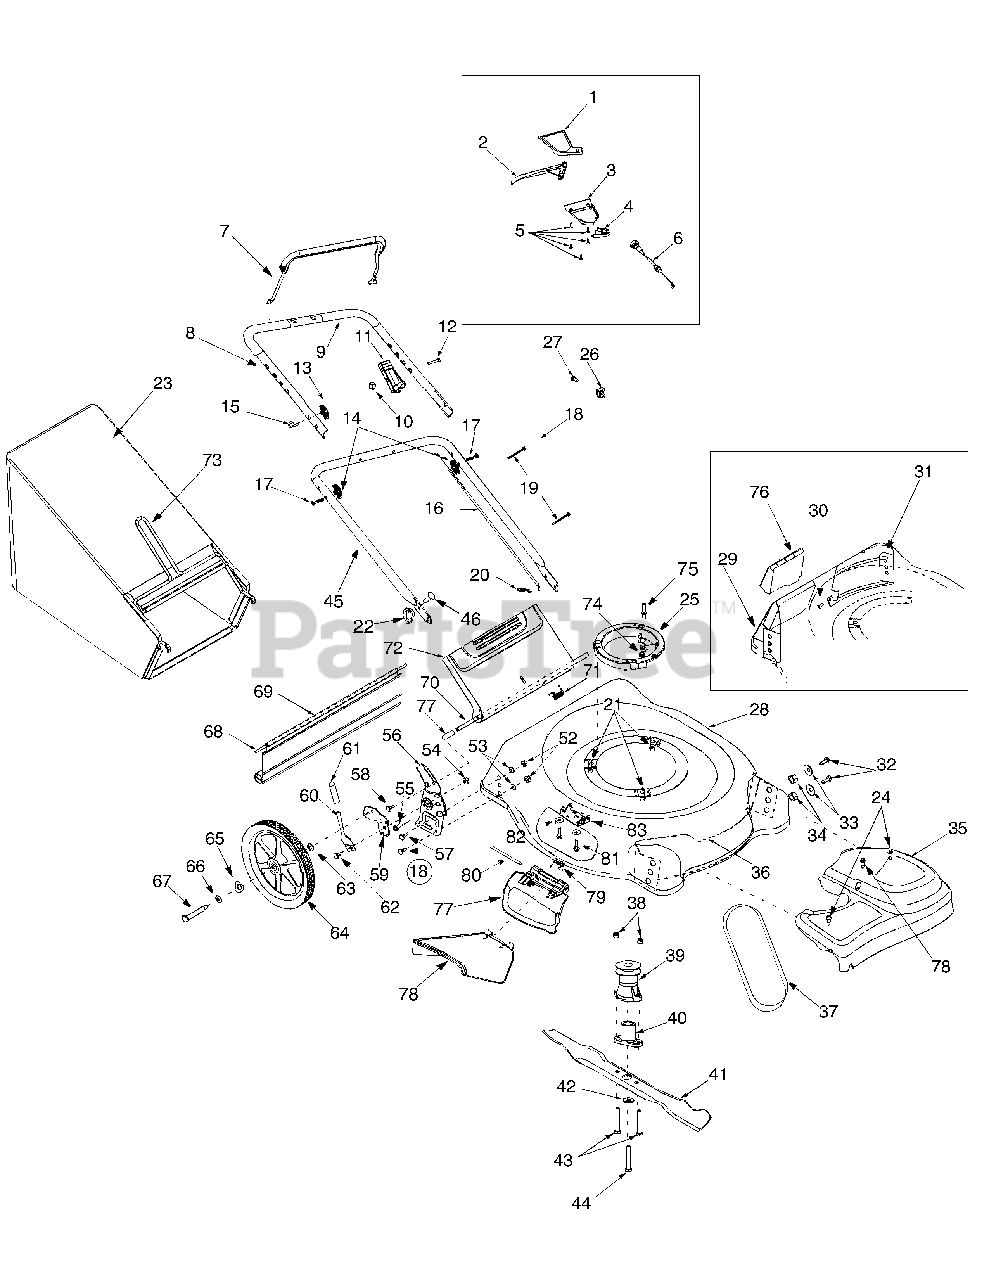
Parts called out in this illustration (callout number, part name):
1	Upper Drive Cover
2	Drive Lever
3	Lower Drive Cover
4	Mounting Cap
5	Screw # 10-16 x .75
6	Drive Cable
9	Foam Grip, 9"
10	Hex Lock Nut, 1/4-20
11	Control Housing
12	Oval C-Sunk Screw 1/4-20 x 1.
13	Handle Knob
14	Handle Knob
15	Eye Bolt
16	Control Cable, 40.5"
17	Carriage Bolt 5/16-18 x 2.0
18	RH Bracket Ass’y
19	Cable Tie
20	Cotter Pin
21	Self-Tapping Screw
22	Wing Knob
23	Grass Bag
24	Screw # 12 x .457
25	Engine Spacer
26	Clamp Casing
27	Hex Screw TT #10-32 x .625
30	Screw AB: 1/4-14: .625
32	Hex Screw 3/8-16 x .75
33	Bell Washer .39 x 1.13 x .062
34	Hex Nut 3/8-16
35	Transmission Cover (Black)
38	Hex Nut 1/4-20
39	Drive Pulley
40	Blade Adapter
41	21" Mulching Blade
42	Flat Washer .516 x 1.5 x .134
43	Hex Screw 1/4-20 x 1.50
44	Hex Screw 3/8-24 x 2.50
46	Carriage Bolt, 1/4-20 x .75"
52	Hex Lock Nut
53	Bell Washer .39 I.D. x 1.38 O.D.
54	Hex Flange Lock Nut 3/8-16
55	Hex Scr. w/Washer 1/4-14 x .625
57	Hex Bolt 3/8-16 x 1.0"
58	Pan Head Screw
59	RH Pivot Bar
60	Height Adj. Lever
61	Foam Grip
62	Shoulder Scr .500 Dia. x .434
63	Washer .401 x .870 x .063
64	Wheel, 14 x 2 Grey
65	Spring Washer .50 I.D. x 1.0 O.D.
66	Flat Washer .510 x 1.373 x .04
67	Shoulder Screw
68	Wire
69	Rear Trailing Shield
70	Pivot Rod
71	Torsion Spring
74	Hex Nut
75	Screw
76	Plastic Mulching Baffle
77	Mulching Plug (Hinged)
78	Chute Deflector
79	Torsion Spring
80	Hinge Pin
81	Tapp Scr. 1/4-20 x .500
82	Bell Washer .265 x .75 x .062
